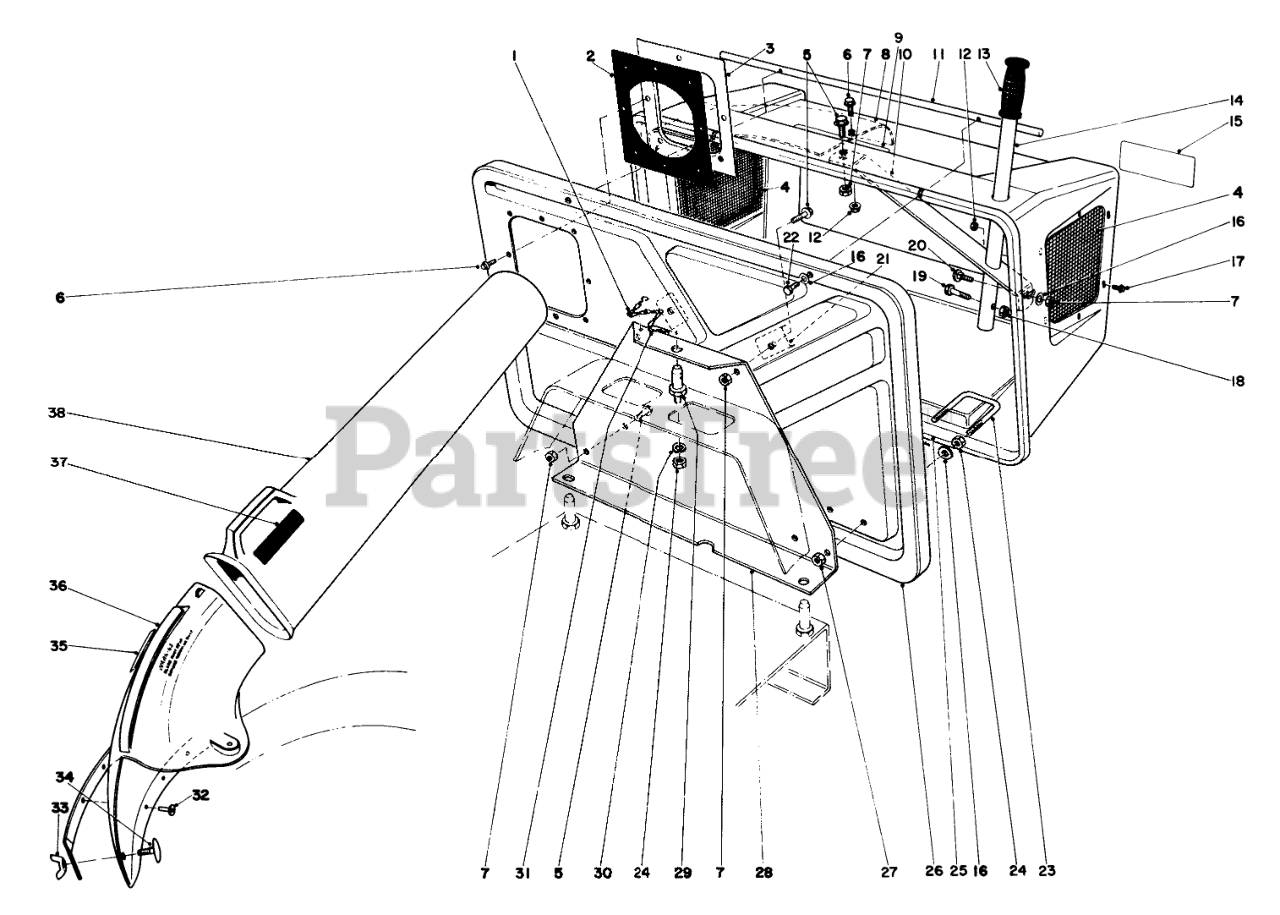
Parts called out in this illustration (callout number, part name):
1	6-LINK CHAIN W/HOOK
1	NUT-LOCK, CONE
2	INLET SEAL
2	Decal-Warning
3	FRAME SEAL
3	COUNTERWEIGHT B
4	SCREEN
4	SCREW-HH
5	SCREW-HHF
6	SCREW
7	NUT-HEX, SIDE DEFORM
8	DEFLECTOR
9	DECAL
10	HANDLE GUIDE
11	PIVOT ROD
12	NUT-LOCK, FLANGE
14	HANDLE TUBE
15	EASY EMPTY BAG DECAL
16	WASHER-FLAT
17	SCREW-HWH
18	NUT-HEX, SIDE DEFORM
19	SCREW-HH
20	SCREW-CARR
21	Retainer
22	SCREW-HH
23	LATCH
24	NUT-HEX
25	HOPPER
27	NUT-LOCK, NI
28	Plate Mounting
29	Pin-Mounting
30	WASHER-LOCK
31	HAIRPIN COTTER
32	RIVET 3/16 X 7/16
33	NUT-WING
34	STEP BOLT
35	Decal-Chute
36	Chute Assembly(Incl. Ref. #32 & 35)
37	Decal Duct
38	Duct Assembly (Incl. Ref. #37)
